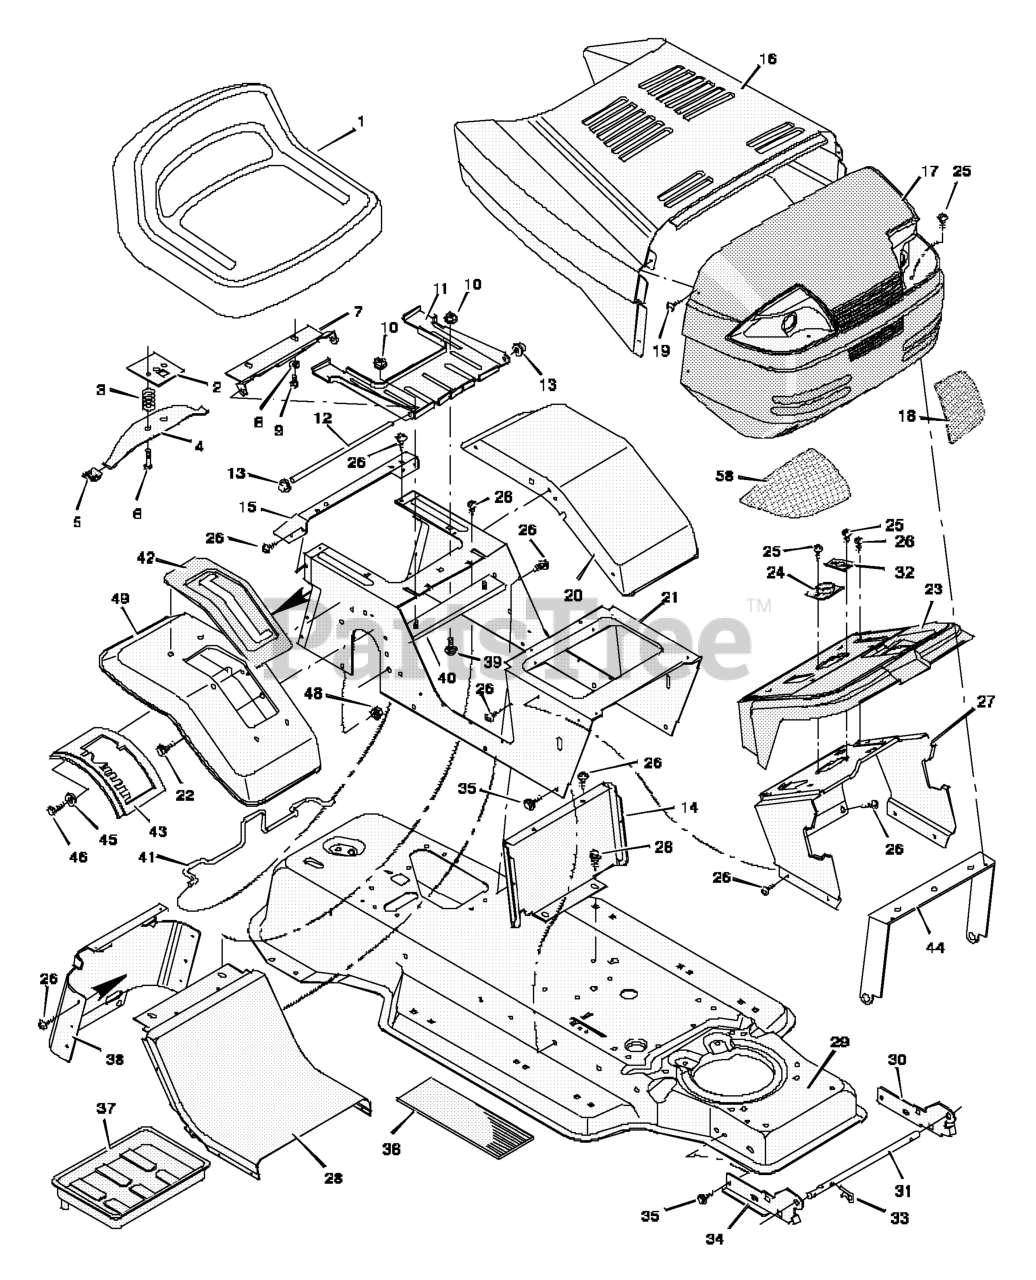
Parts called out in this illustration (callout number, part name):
2	Plate Assembly, Switch
3	Spring, Compression
4	Spring, Seat
5	Glide, Spring
6	Bolt, Shoulder
7	Support, Seat
8	Lockwasher
9	Bolt, Hex
10	Locknut, Flange
11	Bracket, Pivot
12	Rod, Pivot
13	Cap, Push On
14	Insert, Front
15	Fender, Apron
17	Grille Assembly
18	Lens, Left
21	Console Assembly
23	Dash Panel
24	Bearing, Steering
26	Screw
27	Support, Dash
28	Insert, Rear
29	Frame Assembly
30	Bracket, Left Grille
31	Rod, Pivot
32	Bearing
33	Pin, Hair
34	Bracket, Right Grille
37	Tray, Battery
38	Cap, Console
39	Bolt
40	Channel Assembly
41	Clamp, Battery
42	Cover, Shift
43	Gate, Shift
44	Brace, Grille
45	Washer
46	Bolt, Hex
48	Locknut
49	Fender, SOG
58	Lens, Right
